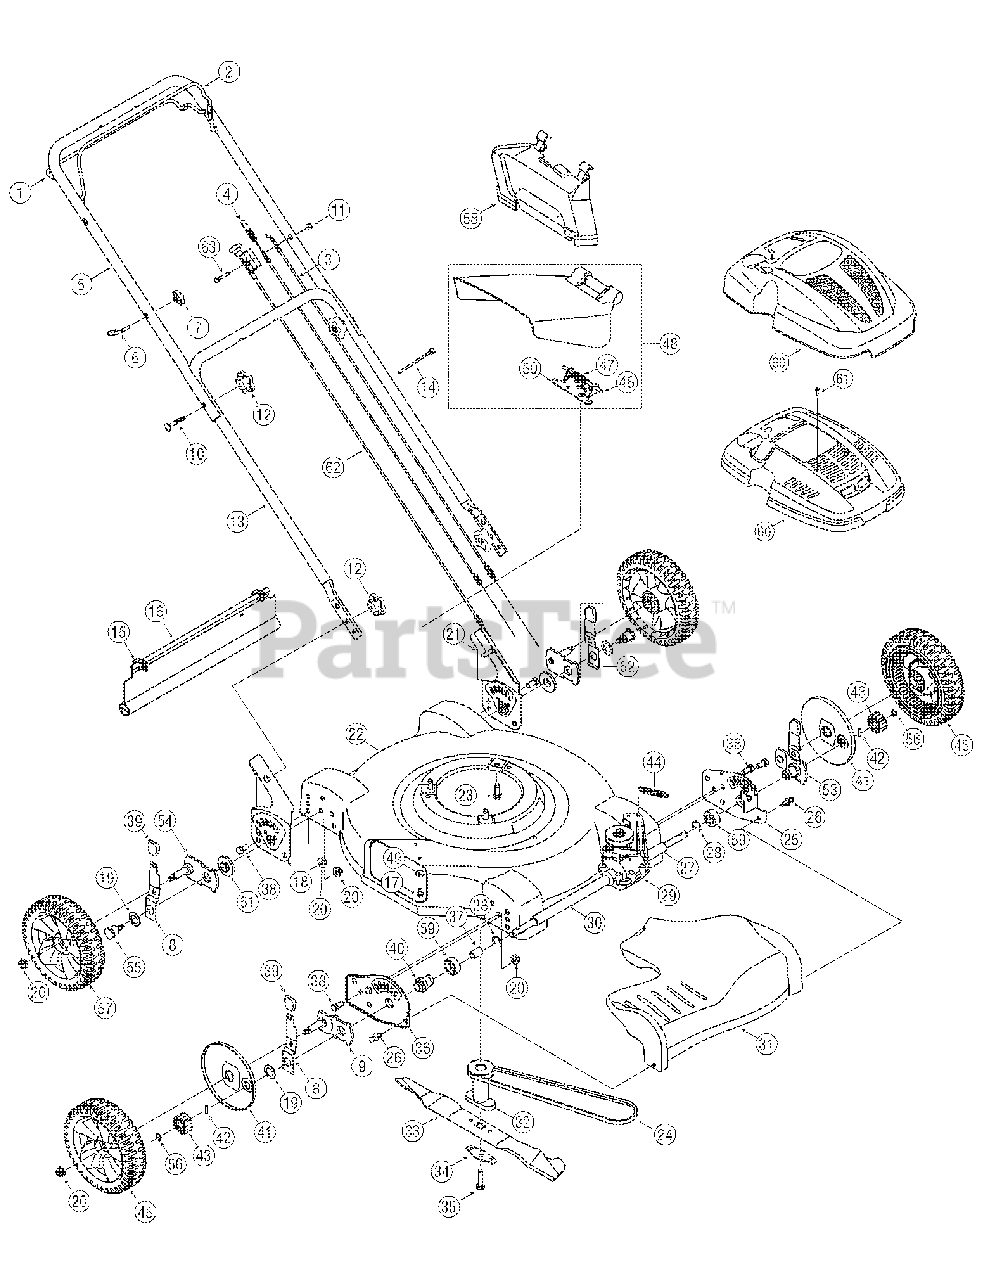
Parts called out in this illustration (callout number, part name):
1	Drive Control
3	Blade Control Cable
4	Drive Control Cable
6	Eye Bolt
7	Wing Nut, 1/4-20
8	Spring Lever
9	Pivot Arm Assembly
10	Carriage Bolt, 5/16-18 x 2.0
11	Flange Lock Nut, 1/4-20
12	Star Knob
14	Cable Tie
15	Hinge Clip
16	Trail Shield
17	Hex Screw, 1/4-20 x.500
20	Lock Nut, 3/8-16
23	Hex Washer Scr., 3/8-16 x 1.0
24	V-Belt, 3L x 32.90
26	Rivet
27	Sleeve Spacer, .550 ID x 2.22
28	Retainer Ring
29	Transmission Assy. Comp.
30	Sleeve Spacer, .550 ID x 8.51
31	Transmission Cover
32	Blade Adapter
33	22" Mulching Blade
34	Bell Blade Support
35	Hex Cap Screw, 3/8-24 X 1.5
37	Slv. Bearing, .502 x.627 x 1.00
38	Hex Cap Screw, 3/8-16
39	Adjustment Knob
40	Bearing Support
41	Wheel Dust Cover
42	Pin
43	Spur Gear 14T - RH
43	Spur Gear 14T - LH
44	Ext. Spring, .47 OD x 2.50
45	Front Wheel 8 x 1.8
46	Hinge Pin
47	Torsion Spring
48	Side Discharge Assembly
49	Bell Washer, .265 ID x .75OD
50	Deflector Chute Adapter
51	Height Adjustment Bearing
52	Rear Hgt. Adj. Lever Assembly
53	Front Lever Assembly
54	Rear Pivot Arm Assembly
55	Shoulder Screw, 3/8-16
56	Screw 1/4-20 X .39
57	Rear Wheel 8 x 1.8
58	Mulching Baffle
59	Bearing Support Spacer
60	Engine Shroud (Yellow)
60	Engine Shroud (Gray)
61	Machine Screw, M4X.7
62	Choke Cable
63	Hex Screw, 1/4-20 x 1.50
